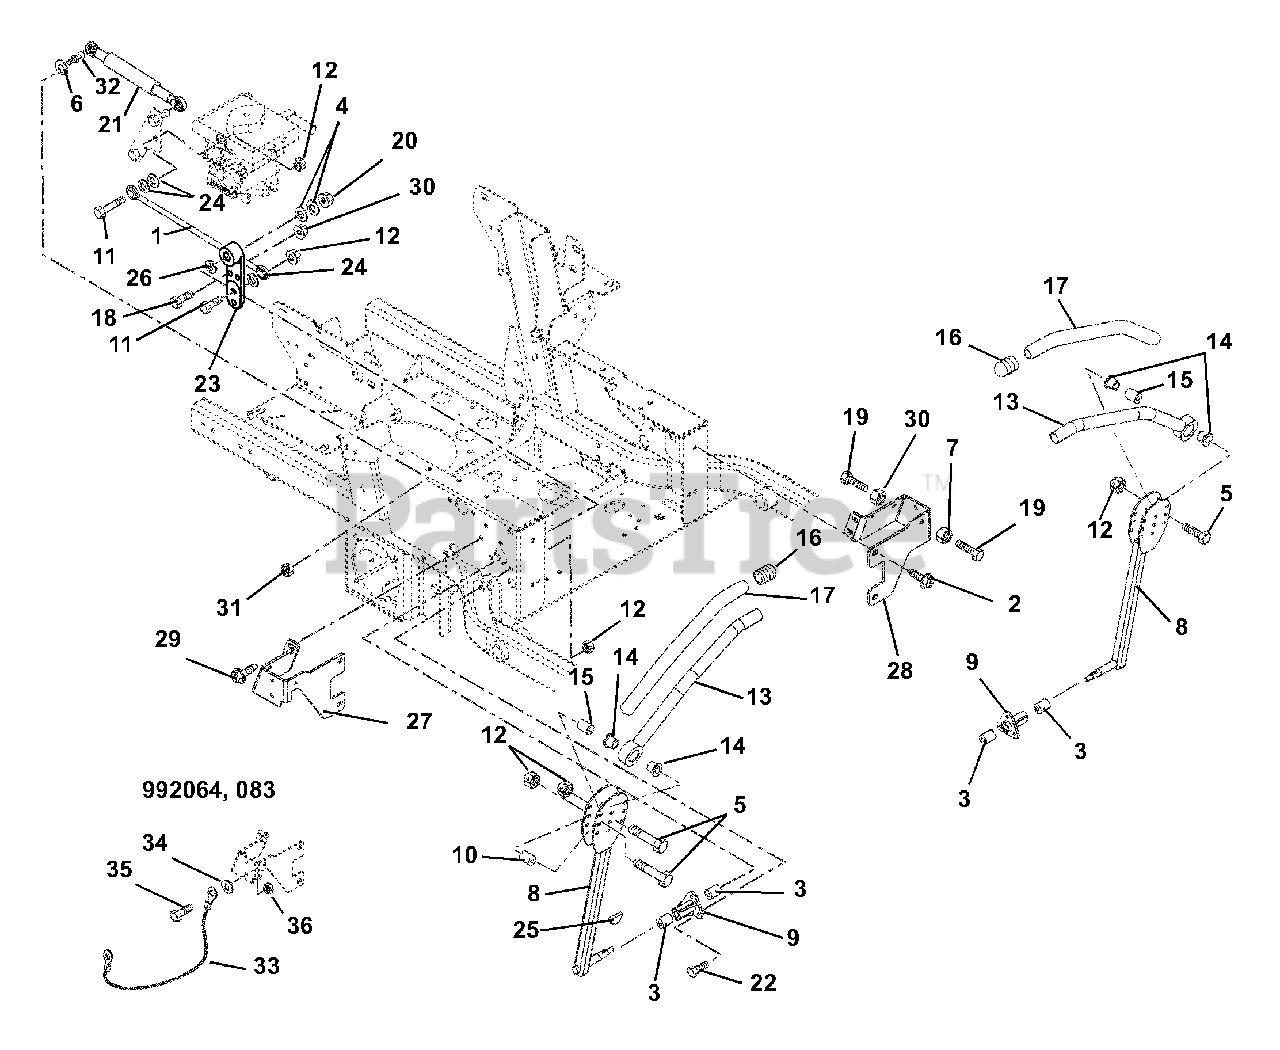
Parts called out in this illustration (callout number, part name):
1	Assembly, Steering Rod
2	Screw, Tapping .38-16 x .75 Hex Washer Head
3	Bushing .625 x .75 x .50
4	Washer, Flat Steel .38 x .875 x .083
5	Bolt, Hex .31-18 x 1.75 Grade 5
6	Washer, Flat Steel .344 x .688 x .065
7	Nut, Hex Jam .375-16
8	Control Arm
9	Housing, Bushing
10	Eccentric
11	Bolt, Hex .31-18 x 1.25 Grade 5
12	Nut, Locking Top Flange .31-18
13	Handle, Left Hand
13	Handle, Right Hand
14	Bushing, Flange Nylon .762 x 1.48 x .44
16	Caplug, Handlebar
17	Grip, Handlebar
18	Bolt, Hex .375-16 x 1.75
19	Bolt, Hex .38-16 x 1.25 Grade 5
20	Nut, Locking Top Flange .38-16
21	Damper, Control
22	Bolt, Hex .31-18 x .75 Grade 5
23	Arm, Pivot
24	Washer, Locking .31 x .078 Regular
25	Key, Woodruff .13 x .63
26	Wave Washer
27	Stop, Steering - Right Hand
28	Stop, Steering - Left Hand
29	Screw, Tapping .38-16 x .50 Hex Washer Head
30	Nut, Locking Jam Center .375-16
31	Nut, Locking Nylon M8-1.25
32	Stud, Ball
33	Cable, Hood (064, 083)
34	Washer, Flat Steel .265 x .50 x .087 (064, 083)
35	Bolt-Hex .25-20 x .75 Grade 5 (064, 083)
36	Nut, Locking Top Flange .25-20 (064, 083)
